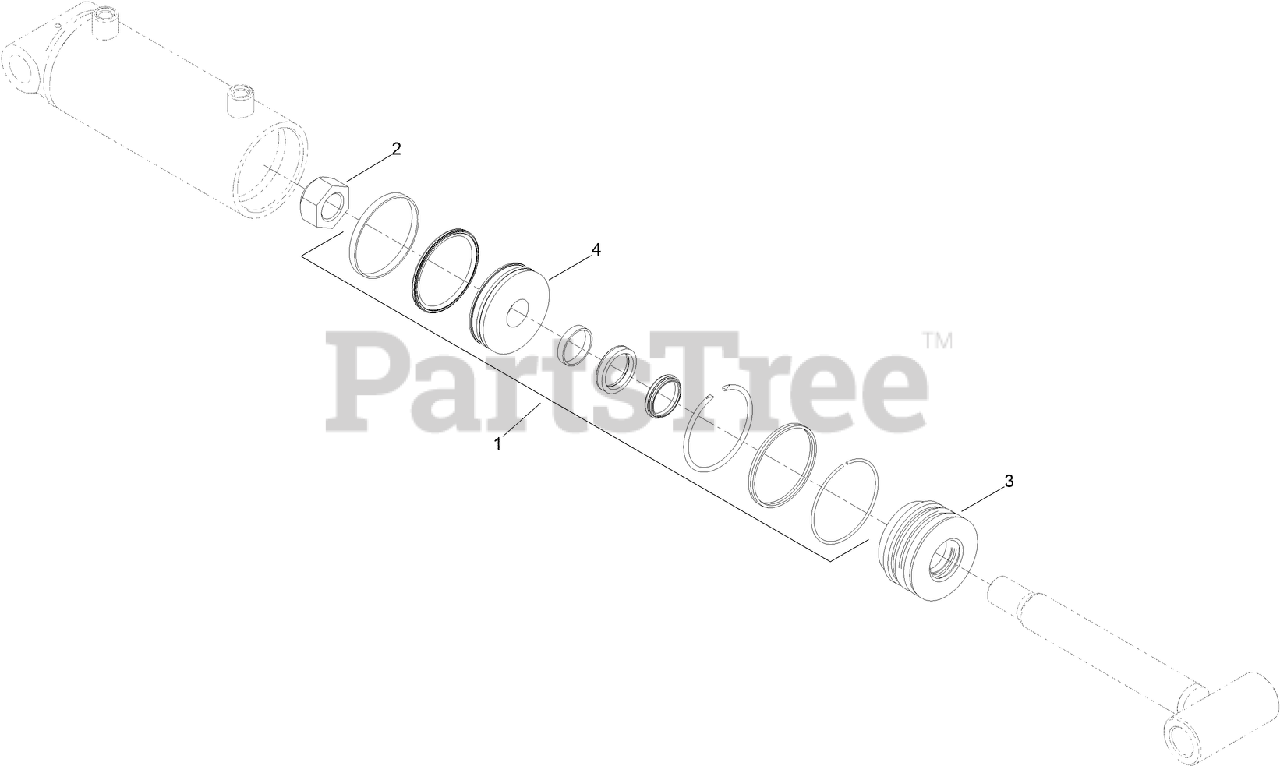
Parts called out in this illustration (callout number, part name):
1	SEAL KIT
2	NUT-HEX
3	HEAD-CYLINDER
4	PISTON
